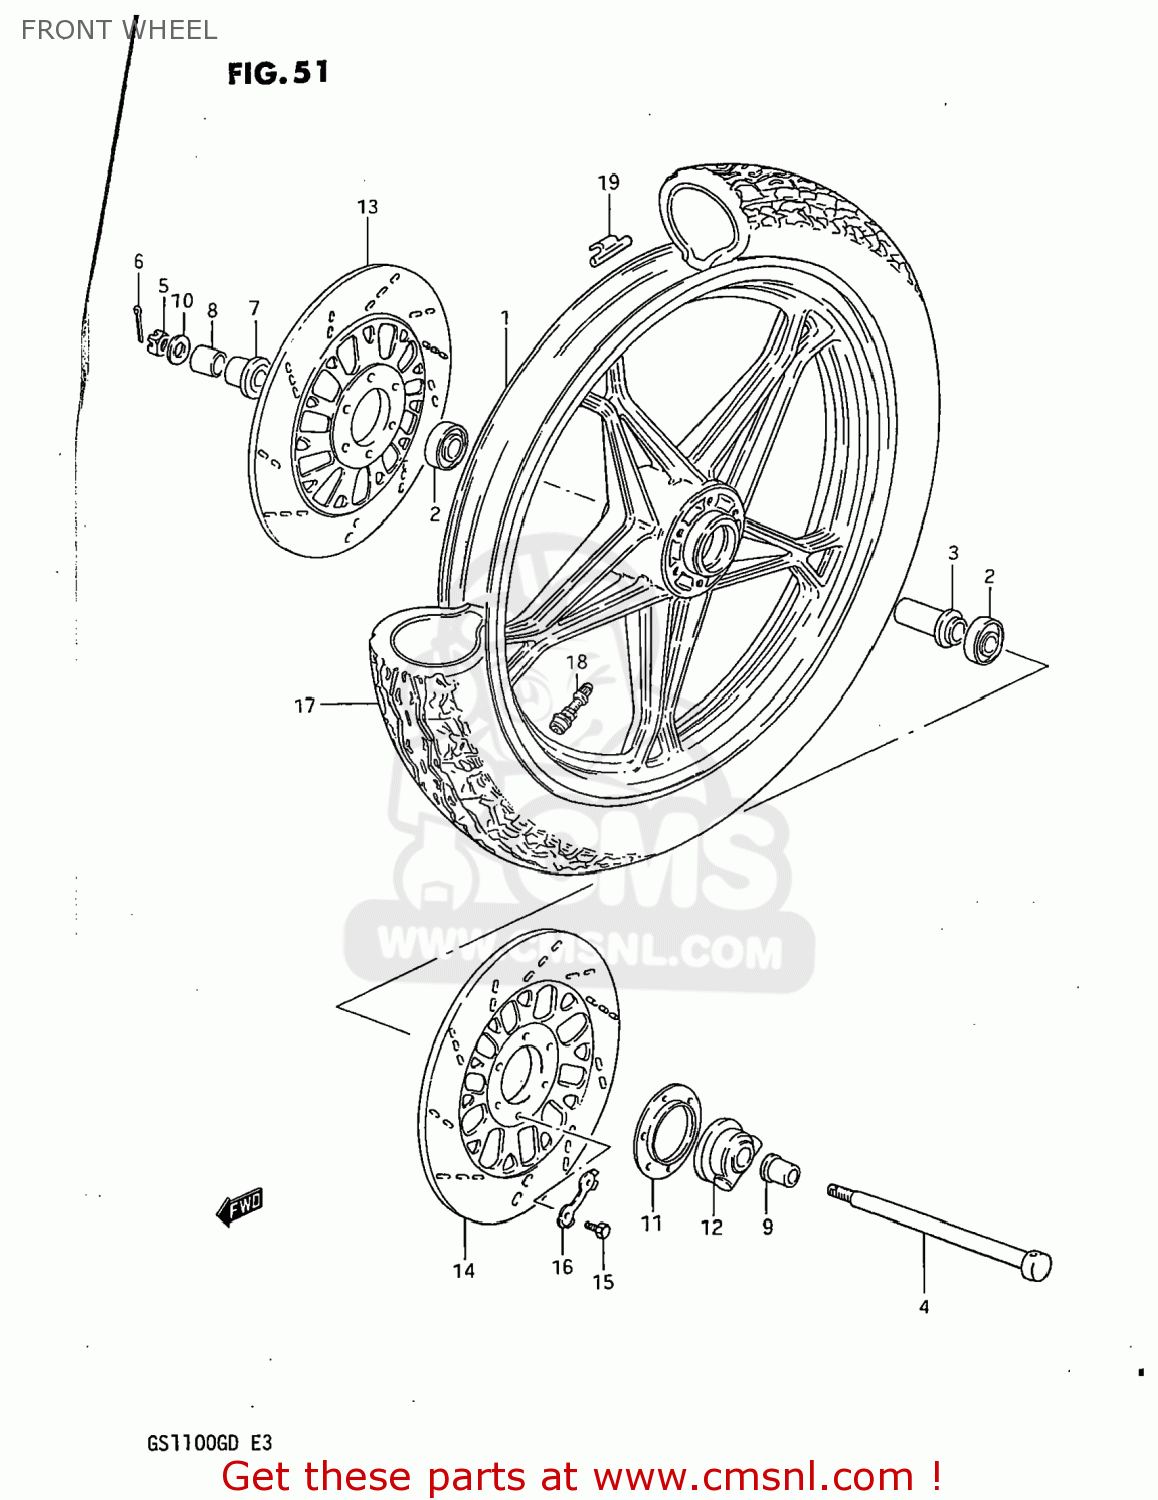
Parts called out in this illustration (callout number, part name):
1	CASTING WHEEL,FRONT 2.15
2	BEARING
3	SPACER,FR HUB BEARING
4	AXLE,FR
5	NUT 12MM
6	COTTER PIN
7	SPACER,FR AXLE,R
8	SPACER,FR AXLE,R
9	SPACER,FR AXLE,L
10	WASHER
11	DUST SEAL,SPEEDOMETER GEAR BOX
12	BOX ASSEMBLY,SPEEDOMETER GEAR
13	DISC,FR BRAKE,R
14	DISC,FR BRAKE,L
15	BOLT(8X25)
16	WASHER
17	TIRE,FRONT
18	VALVE ASSEMBLY,WHEEL RIM,J
19	BALANCER,WHEEL
